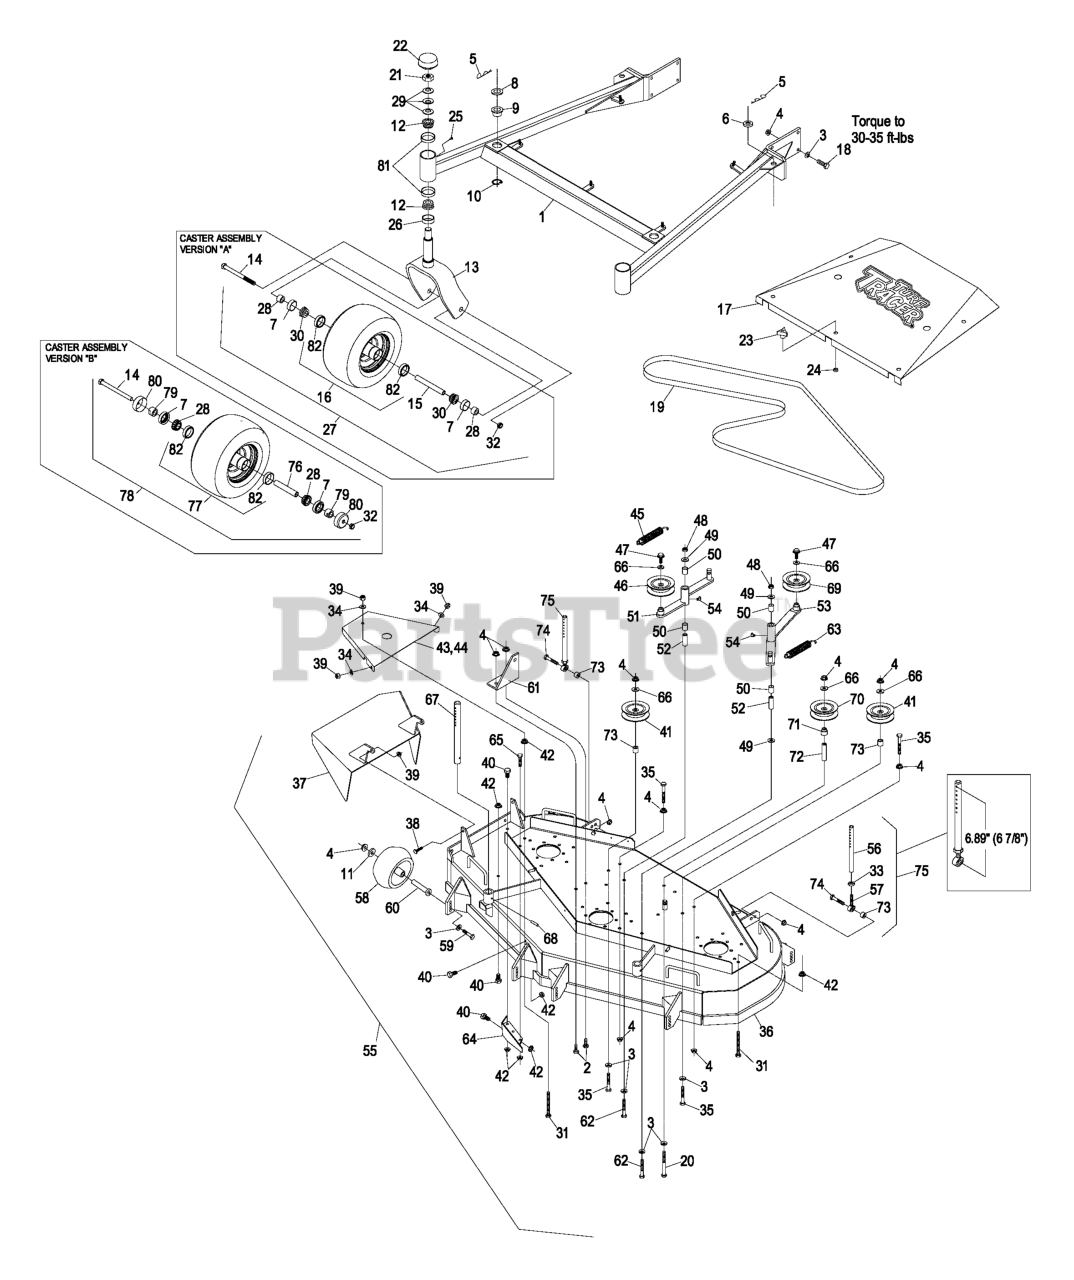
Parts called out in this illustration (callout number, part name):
1	ASM,FMD604 DK SUPPORT, SE
2	SCREW-HH
3	WASHER-BELLEVILLE
4	NUT-HHF, WHIZ
5	PIN,HAIR COTTER
7	SEAL-CASTER
8	SPACER-DECK SUPPORT
9	BUSHING-DECK
10	RING-RETAINING
12	Cone-Bearing Tapered Roller
13	WLD, CASTER FORK
14	SCREW-HH
15	SPACER,FRONT CASTER
18	SCREW-HH
19	BELT,MULE DRIVE
20	SCREW-HH
21	NUT-LOCK, NI
22	CAP-GREASE
23	KNOB-3 PRONG
26	SEAL-GREASE
28	SPACER-BEARING
29	WASHER-BELLVILLE
30	BEARING-CONE, TAPERED ROLLER
31	BOLT,TAP HH
32	NUT-HEX
33	NUT-HEX
34	WASHER-FLAT
35	BOLT-CARR
37	WLD,CHUTE FMD604
38	SCREW-HH
39	NUT-LOCK, NI
40	SCREW-HH
41	IDLER,PULLEY
43	SHIELD,BELT RH
44	SHIELD,BELT LH
45	SPRING-EXTENSION
46	IDLER,PULLEY
47	SCREW-HHF
48	NUT-LOCK, NI
49	WASHER-FLAT
50	SLEEVE-BEARING
51	ASM,IDLER ARM
52	BUSHING-PIVOT, IDLER
53	ASM,IDLER ARM
54	FITTING-GREASE, 90 DEG
55	Complete Deck Assy
56	LINK,SUPPORT
57	BALLJOINT
58	ROLLER-SCALP, ANTI
59	SCREW-HH
60	BUSHING-ROLLER
61	BRACKET,SPRING ANCHOR
62	SCREW-HH
63	SPRING-EXTENSION
64	WLD,BAFFLE DISCHARGE
65	SCREW-HH
66	WASHER-FLAT
67	ROD,DECK SUPPORT
69	PULLEY-IDLER
70	PULLEY-IDLER
71	BUSHING,IDLER
72	SPACER-ANCHOR, CLUTCH
74	SCREW-HH
78	WHEEL AND TIRE ASM
79	SPACER-NUT
80	GUARD-SEAL
81	CUP-BEARING
82	BEARING-CUP
